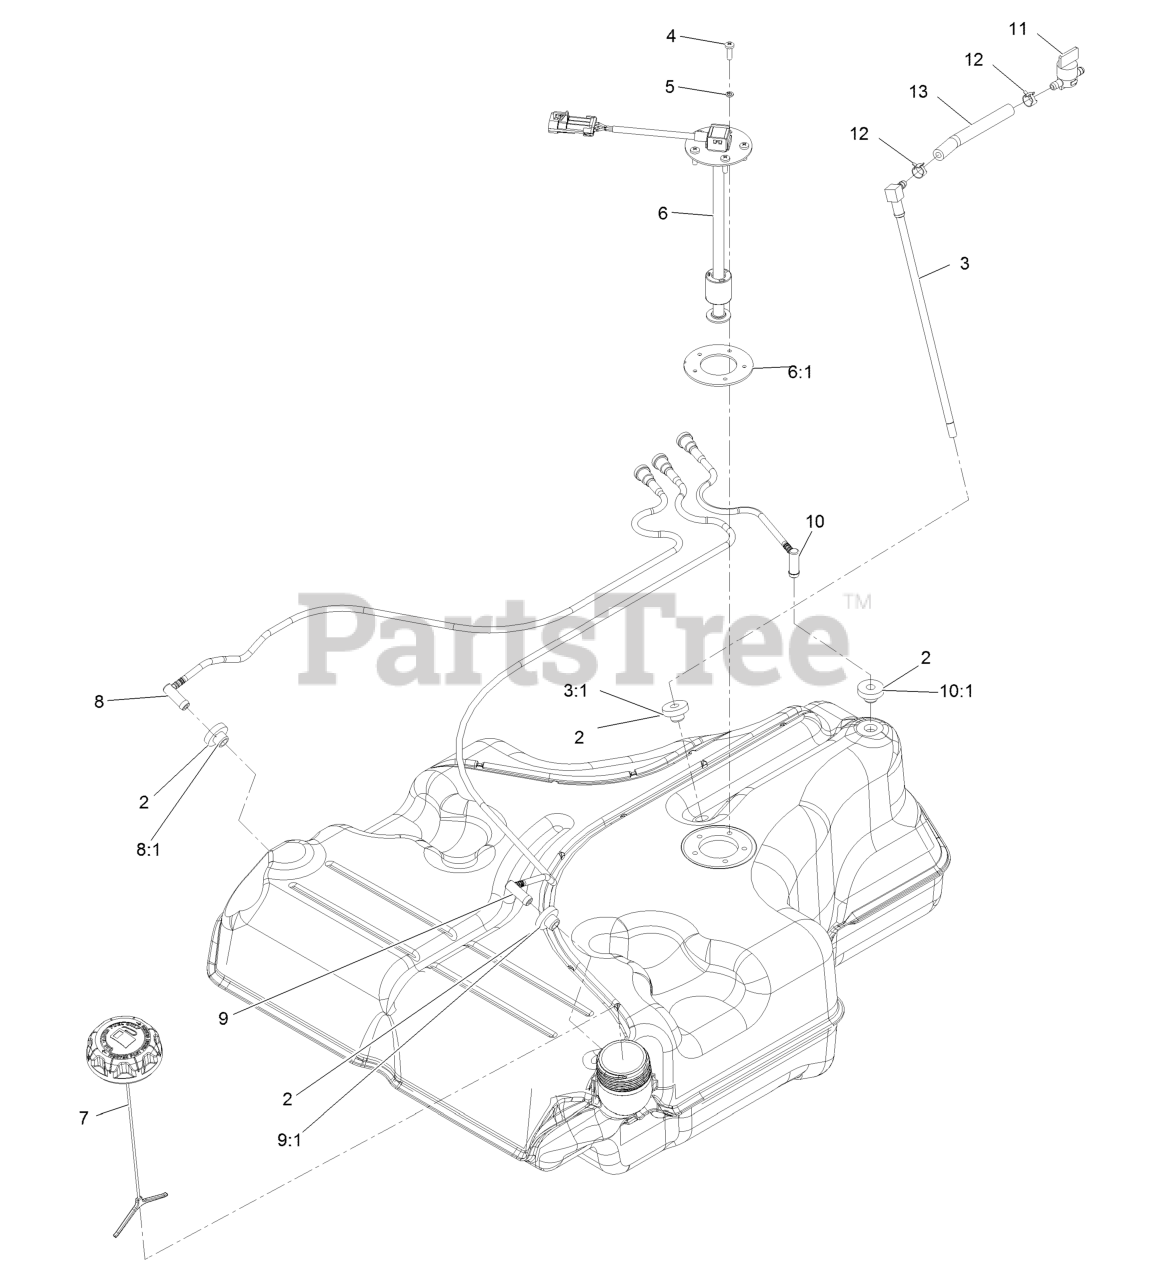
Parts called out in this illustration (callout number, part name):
2	Bushing
3	Fuel Line Kit (With Grommet)
3:1	Bushing
4	Screw-PPH
5	Washer-Lock
6	Float-Sender, Fuel
6:1	Gasket-Sender
7	Cap-Fuel, Ratcheting
8	RH Vent Line Kit (With Grommet)
8:1	Bushing
9	LH Vent Line Kit (With Grommet)
9:1	Bushing
10	Rear Vent Line Kit (With Grommet)
10:1	Bushing
11	Valve-Fuel
12	Clamp-Hose
13	Hose-Fuel
